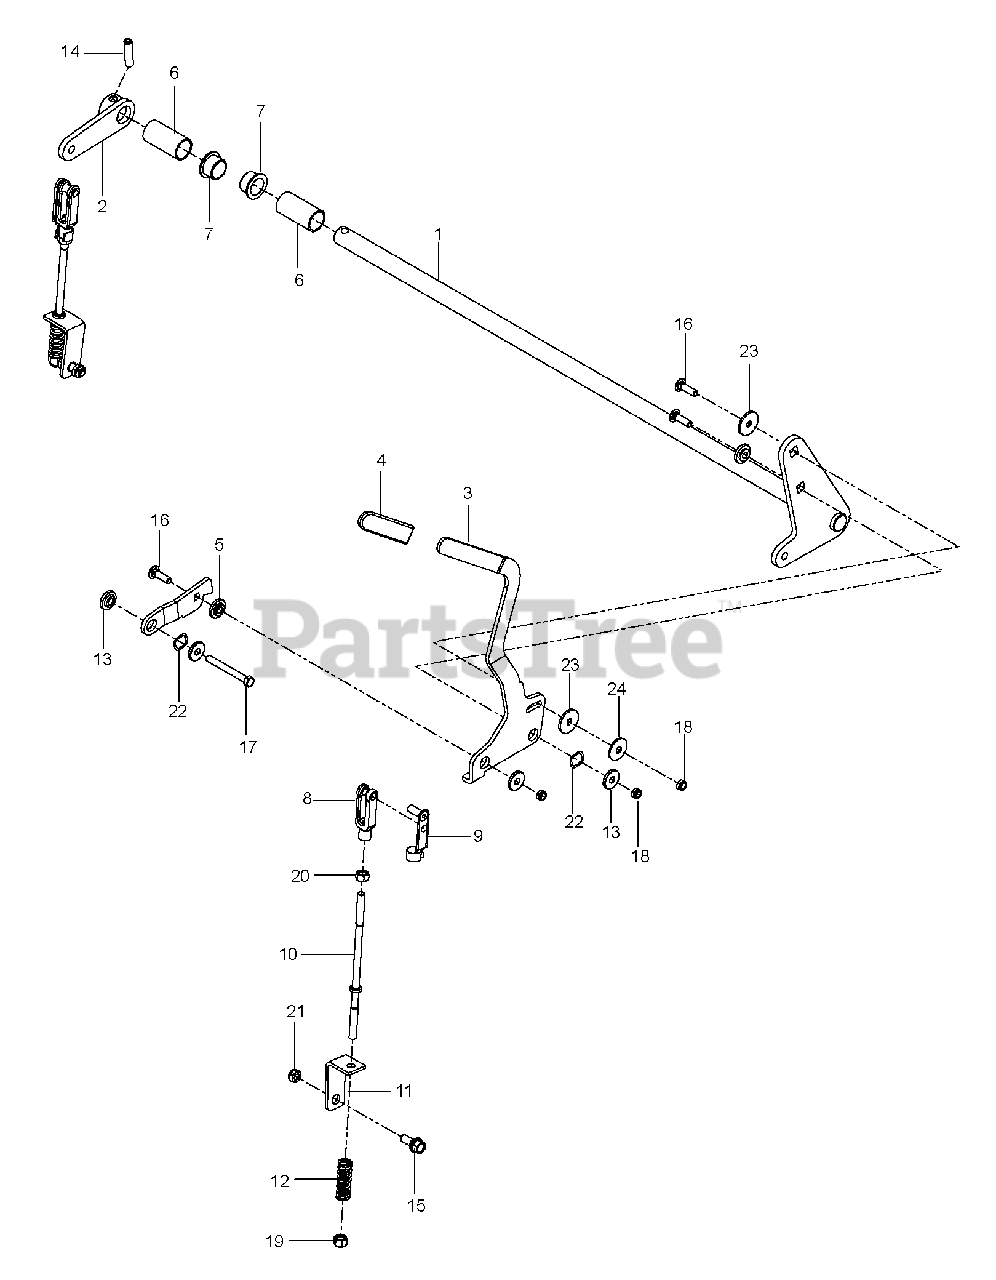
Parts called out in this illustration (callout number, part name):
1	SHAFT, BRAKE, WELDED
2	ARM, BRAKE, RT
3	LEVER.BRAKE.BLACK
5	LINK, FOLLOWER
6	SPACER, SHAFT, BRAKE
7	BEARING, FLANGE
8	YOKE 5/16 ADJ CLEVIS
9	PIN, CLEVIS SPRING 5/16
10	LINKAGE, BRAKE
11	BRKT, BRAKE, BLK
12	SPRING, ENGAGEMENT
13	BUSHING, BRAKE
14	5/16 DIA ROLL PIN
15	BOLT, SHOULDER
16	RHSNB 3/8-16 X 1-1/4
17	HCS 3/8-16 X 3-1/4 GR5 ZD
18	NUT HEX 3/8-16 NYLON, THIN
19	NUT 5/16F NYLOC
21	5/16-18 THIN PROF NY
22	WASHER, .825 X 1.087, WAVE
23	WASHER, FRICTION, 1/8
24	CONE WASHER
